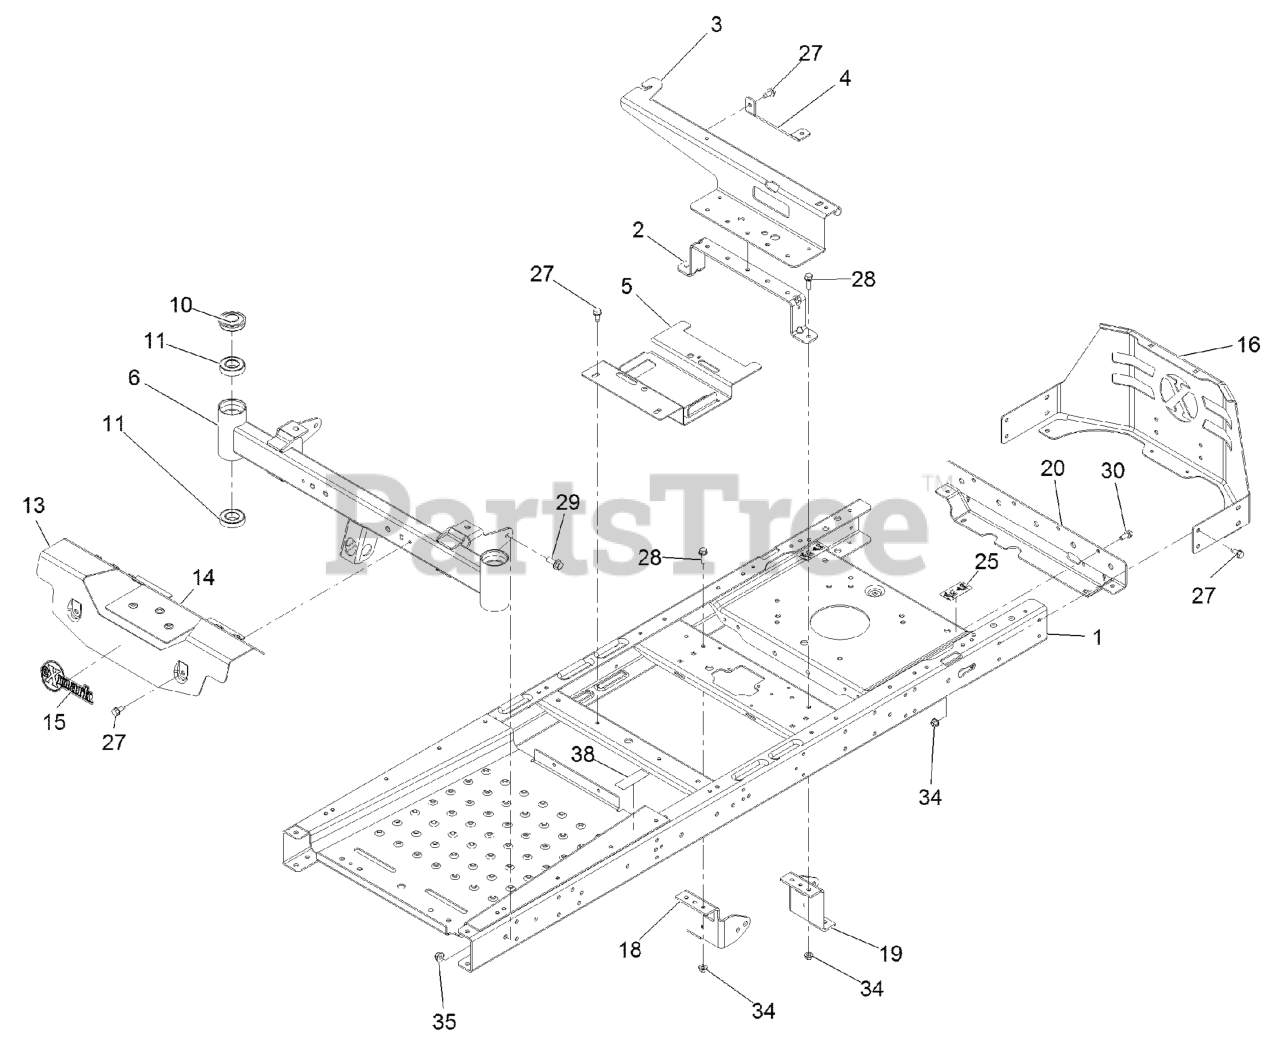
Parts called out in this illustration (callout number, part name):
1	FRAME ASM
2	BRACE-SEAT, REAR (NARROW)
3	SUPPORT-POD
4	SUPPORT-TANK, REAR
5	BRACKET-BATTERY
6	AXLE-FRONT, NARROW
10	Cap-Grease
11	BEARING-BALL
13	FOOTREST ASM
14	DECAL-WARNING
15	DECAL-EXMARK LOGO
16	GUARD-ENGINE, NARROW
18	MOUNT-HYDRO, FRONT (RIGHT
19	MOUNT-HYDRO, FRONT (LEFT)
20	CROSSMEMBER-REAR, NARROW
25	DECAL-BYPASS
27	Screw-HWH 5/16-18 X 3/4 Tf
28	SCREW-HHF
29	SCREW-HHF 3/8-16 X 1
30	SCREW-HHF
34	NUT-HF, NI
35	NUT-HF, NI
38	DECAL-BRAKE, PARKING
